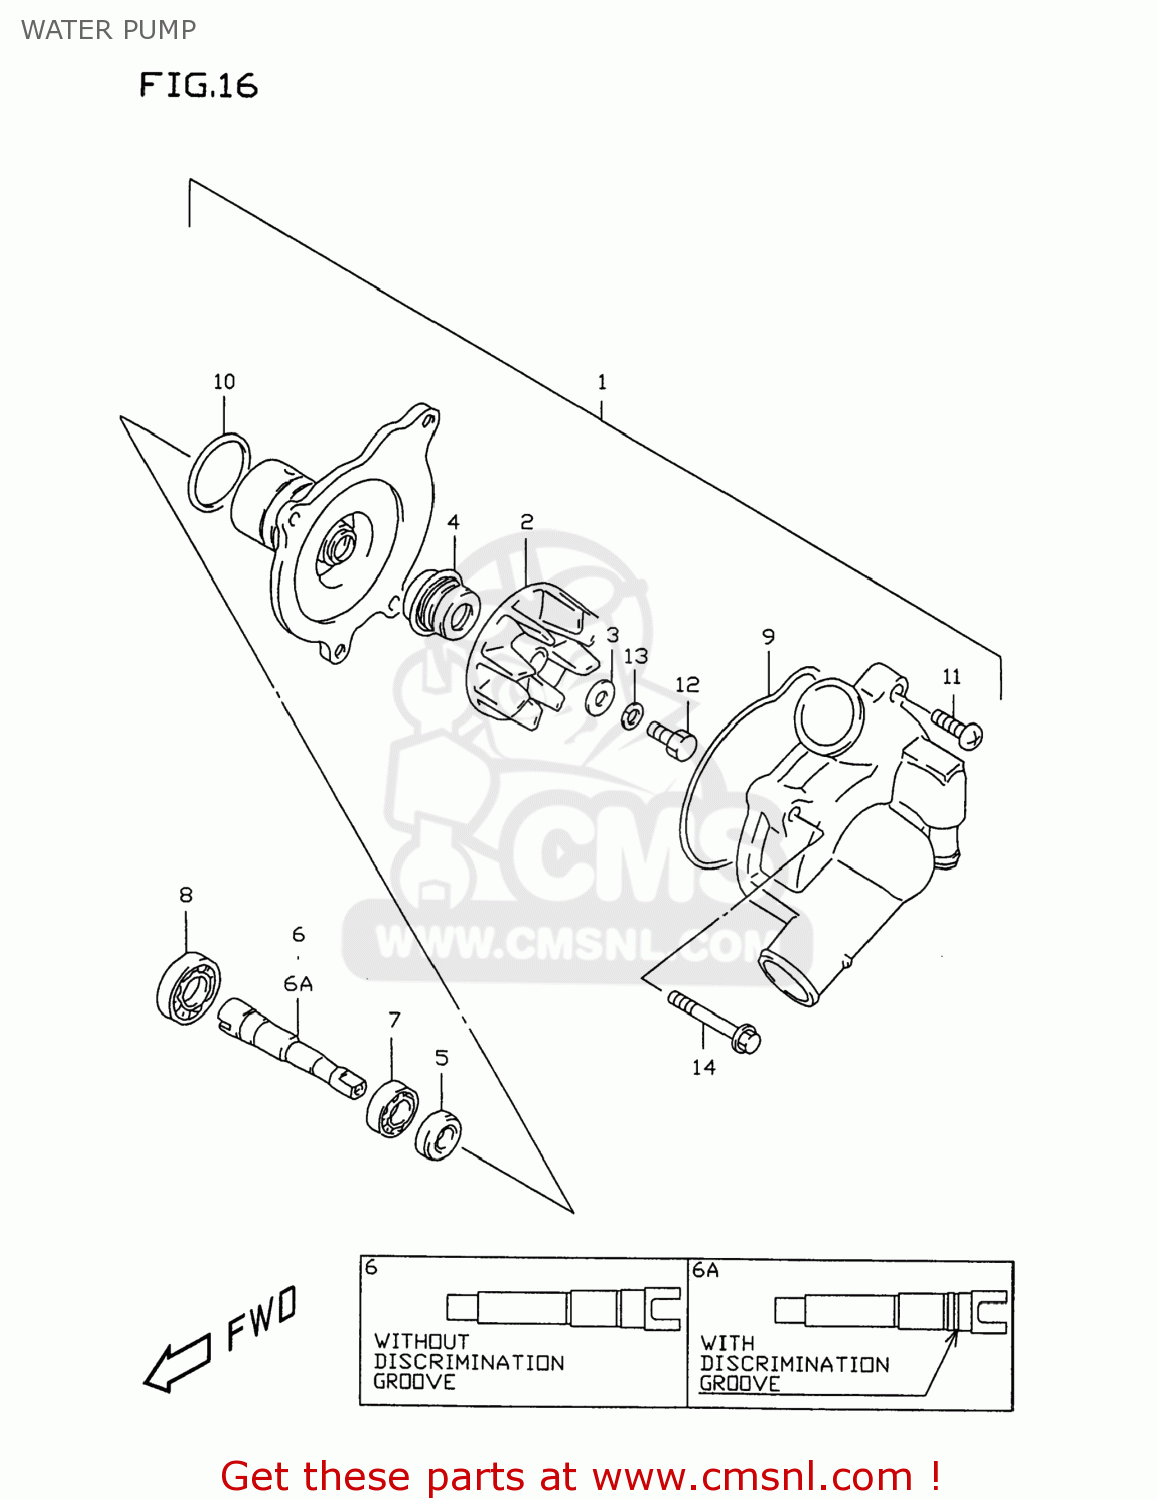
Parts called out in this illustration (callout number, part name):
1	PUMP ASSY,WATER
2	IMPELLER
3	GASKET(6X15X2.2) (NAS)
4	SEAL,MECHANICAL
5	SEAL,OIL(10X21X5)
6	SHAFT,WATER PUMP
6A	SHAFT,WATER PUMP
7	BEARING(10X26X8)
8	BEARING(12X28X8)
9	O RING
10	O RING,WATER PUMP HOLDER
11	SCREW 6X16
12	BOLT(6X13)
13	WASHER
14	BOLT
